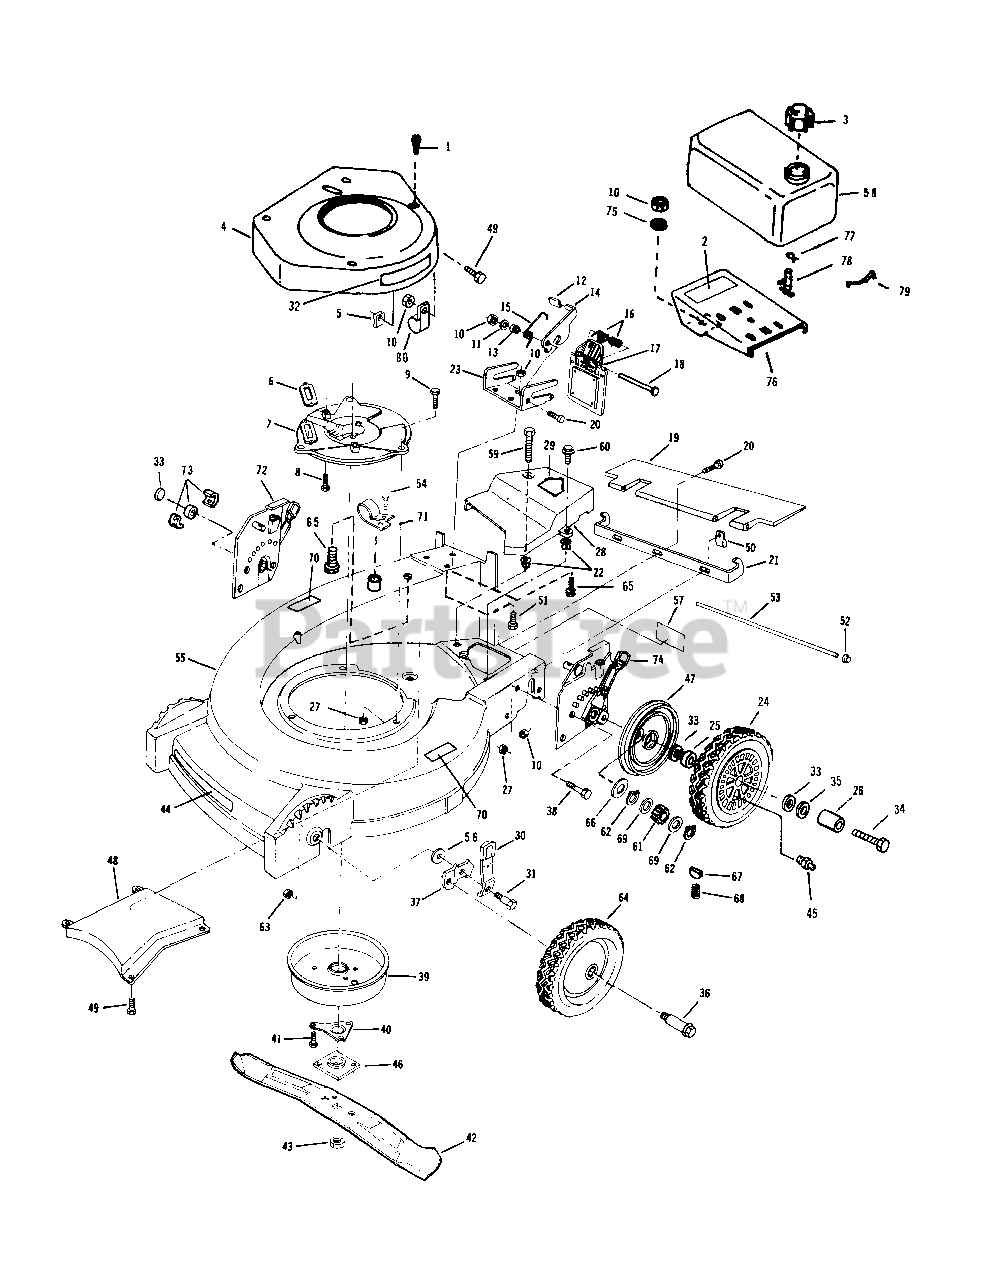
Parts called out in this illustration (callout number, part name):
1	Screw
2	Decal-Fuel Mix
3	Fuel Cap
4	Shroud-Engine
5	Retainer
6	Gasket-Exhaust
7	Plate-Muffler
8	Screw-Muffler to Block
9	Screw-Muffler Plate to Housing
10	Nut-Latch Bracket, Trailing Shield and Tank Bracket
11	Washer
12	Knob-Latch
13	Stepped Spacer
14	Catch-Bag
15	Spring-Latch
16	Spring
17	Door
18	Rod
19	Shield-Trailing
20	Screw-Latch Bracket and Trailing Shield
21	Bracket-Bag Hanger
22	Grommet
23	Hinge Plate
24	Wheel and Tire Assembly
25	Bearing-Wheel
26	Sleeve
27	Nut-Height Adjust, Muffler Plate and Guard to Housing
28	Cover Belt
29	Decal-Blade Contact Warning
30	Knob and Spring Assembly
31	Bolt-Shoulder
32	Decal-Lawn-Boy
33	Washer-Felt-Rear Wheel and Driveshaft
34	Bolt-Wheel
35	Washer-Wheel Bolt-Rear
36	Bolt-Shoulder Wheel
37	Bracket-Wheel Height Adjust
38	Bolt-Height Adjust Assembly
39	Muffler Cover Assembly
40	Support-Crankshaft
41	Screw-Muffler to Muffler Plate
42	Blade 20"
43	Nut
44	Decal-Headliner
45	Fitting-Lubrication
46	Collar and Plate Assembly
47	Cover-Wheel
48	Baffle
49	Screw
50	Clamp-Rod
51	Screw-Fuel Tank Bracket
52	Nut-Rod
53	Rod-Trailing Shield
54	Screw-Clamp to Housing
55	Housing-20"
56	Washer-Wheel Height Adjust
57	Decal-Caution
58	Fuel Tank
59	Screw-Hex Head
60	Screw-Belt Cover
61	Pinion
62	Retaining Ring
63	Nut-Wheel Height Adjust
64	Wheel and Tire Assembly
65	Screw
66	Washer
67	Key
68	Spring
69	Spacer
70	Decal-Height Adjust
71	Clamp-Cable and Primer to Housing
72	Height Adjuster Assembly R.H.
73	Bearing and Retainer Asy.
74	Height Adjuster Assembly-L.H.
75	Washer-Tank Mount
76	Bracket-Fuel Tank
77	Clamp-Fuel Tank
78	Shut-Off Valve and Screen
79	Spring-Fuel Tank Mounting
80	Clamp
